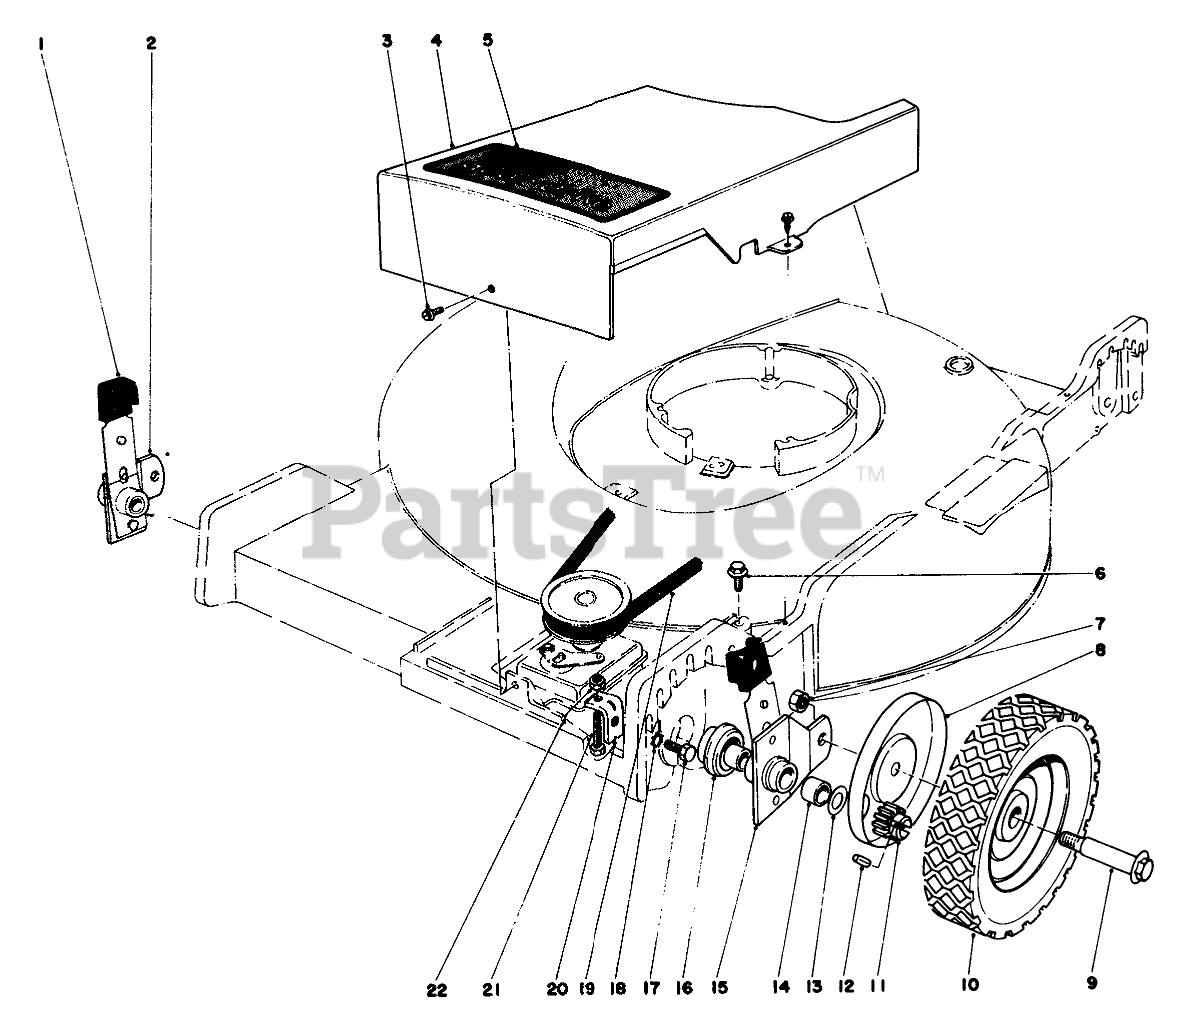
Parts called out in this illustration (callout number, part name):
1	KNOB-ARM
2	Pivot Arm (Incl. Ref. #14)
3	SCREW
4	Belt-Cover
5	Decal Belt Cover
6	SCREW-HWHTF
7	Nut
8	WHEEL COVER
10	Wheel & Tire
11	Pinion
12	PIN-GROOVED
13	WASHER-THRUST
14	BUSHING
15	Pivot Arm (Incl. Ref . #14)
16	End Cap
17	SCREW-HH
18	WASHER-LOCK
19	V-BELT
20	Bracket-Gear Box
21	SCREW
22	NUT-LOCK
